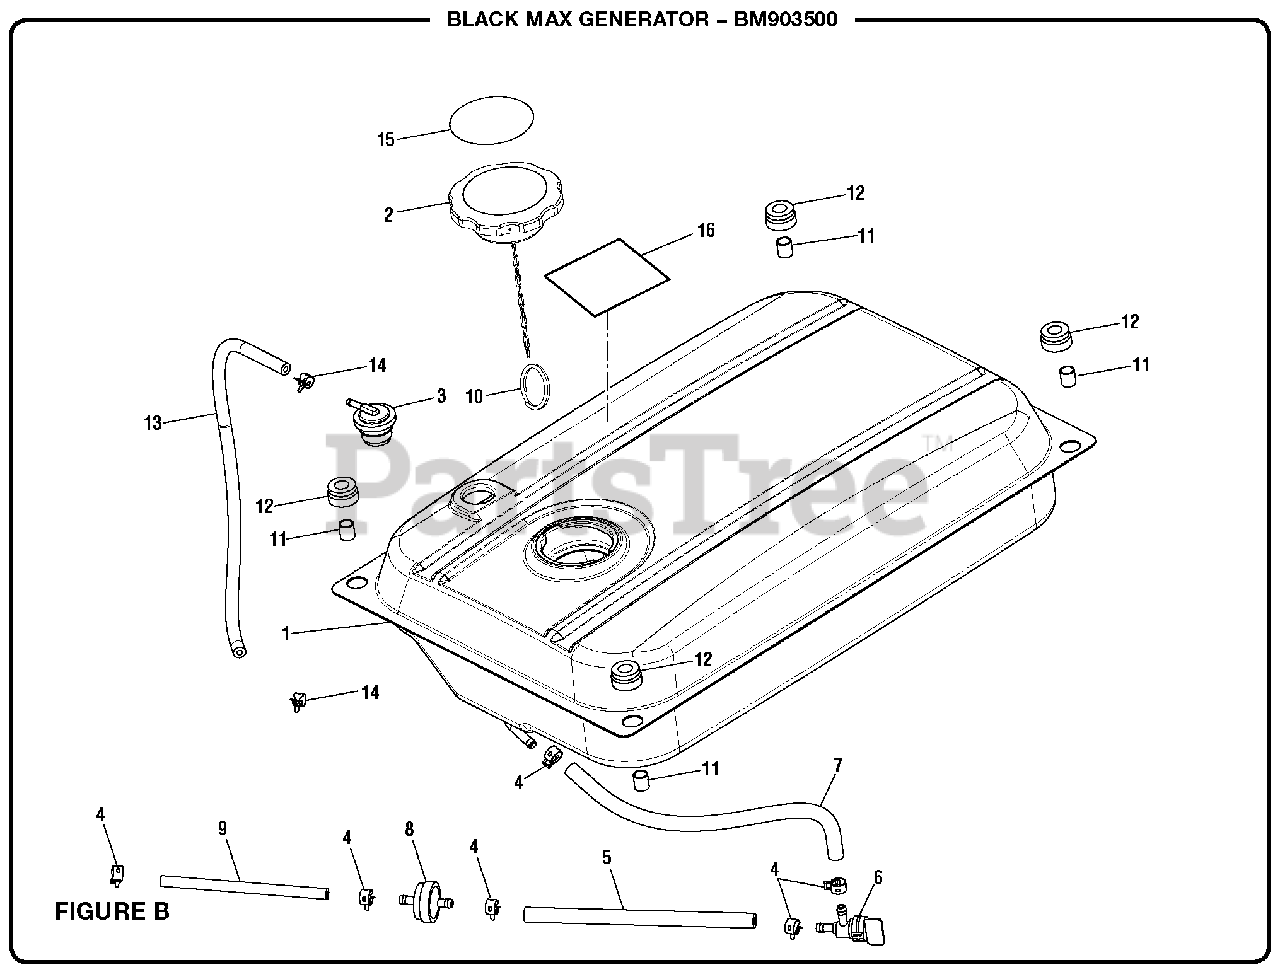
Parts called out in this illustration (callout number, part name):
1	Fuel Tank
3	Fuel Tank Vapor Vent
4	Clamp (1/2 in.)
5	Fuel Hose (45 mm)
6	Fuel Shut Off Valve
7	Fuel Hose (35 mm)
8	Fuel Filter
9	Fuel Line (144 mm)
10	Ring Clip
13	Vent Hose
14	Fuel Line Clamp (7/16 in.)
15	Fuel Stabilizer Label
16	Fuel Stabilizer Label (Sp)
